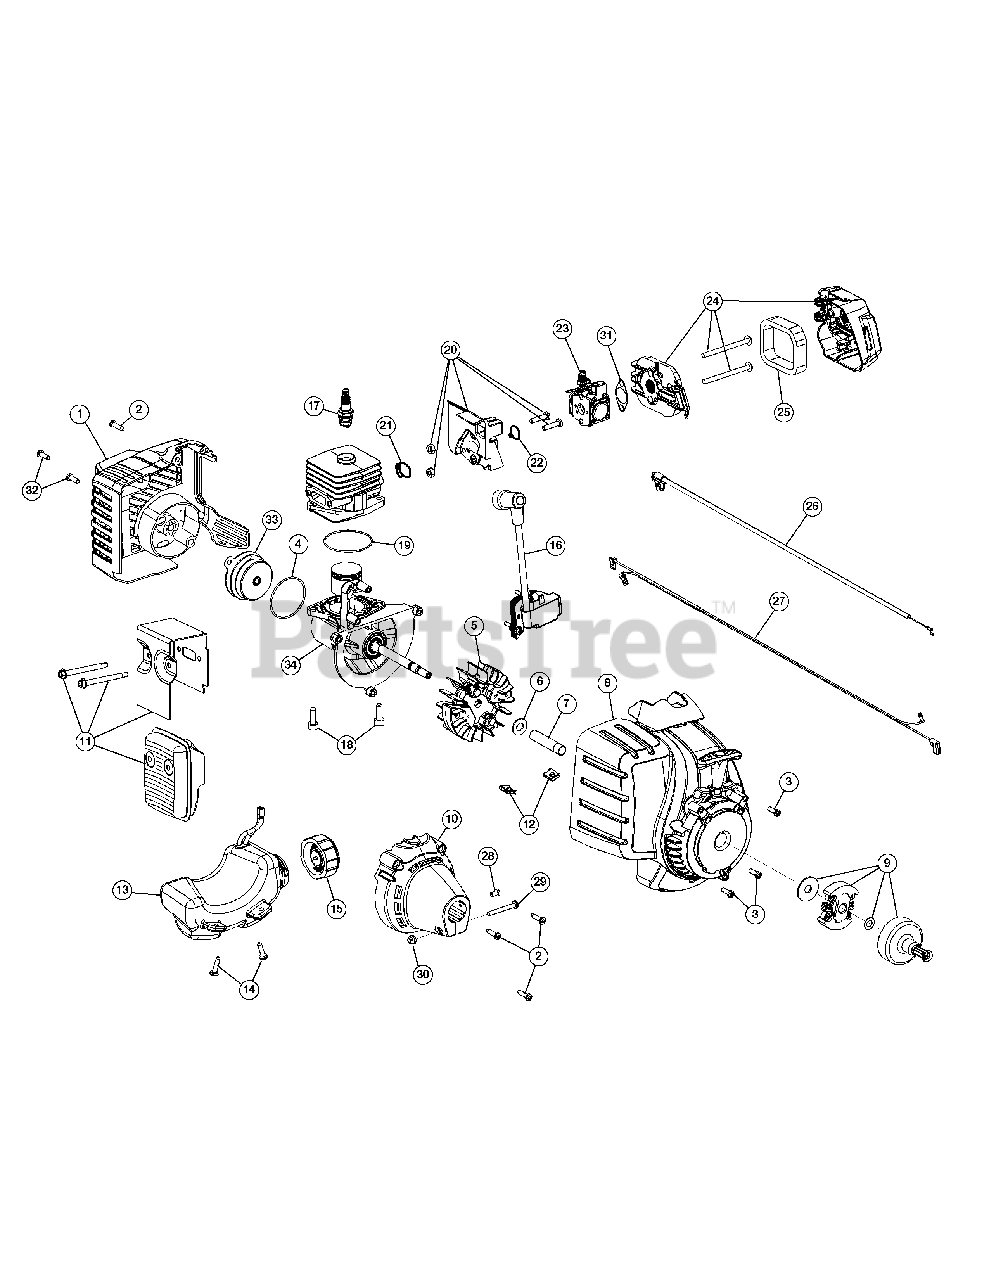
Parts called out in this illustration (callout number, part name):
1	Rear Cover Assembly (Incl. 2 & 32)
2	Cover Screw
3	Housing Screw
5	Flywheel Assembly
8	Starter Housing (Incl. 3 & 12)
9	Clutch Assembly
10	Clutch Cover (Incl. 2)
11	Muffler Assembly
12	U-shaped Nut
13	Fuel Tank Assembly (Incl. 14 & 15)
16	Module Assembly
17	Spark Plug
18	Crankcase Bolt
19	Crankcase O-Ring
20	Insulator Assembly (Incl. 21 & 22)
21	Insulator O-Ring
22	Carburetor O-Ring
23	Carburetor
24	Aircleaner Cover Assembly (Incl. 25)
25	Aircleaner Filter
26	Throttle Cable
27	Lead Wires
28	Anti-rotation Screw
29	Clamp Screw
30	Clamp Nut
31	Air Cleaner Gasket
32	Rear Housing Screw
33	Electric Starter Cover Assembly
34	Short Block Assembly (Incl. 4 - 7 & 16 - 19)
